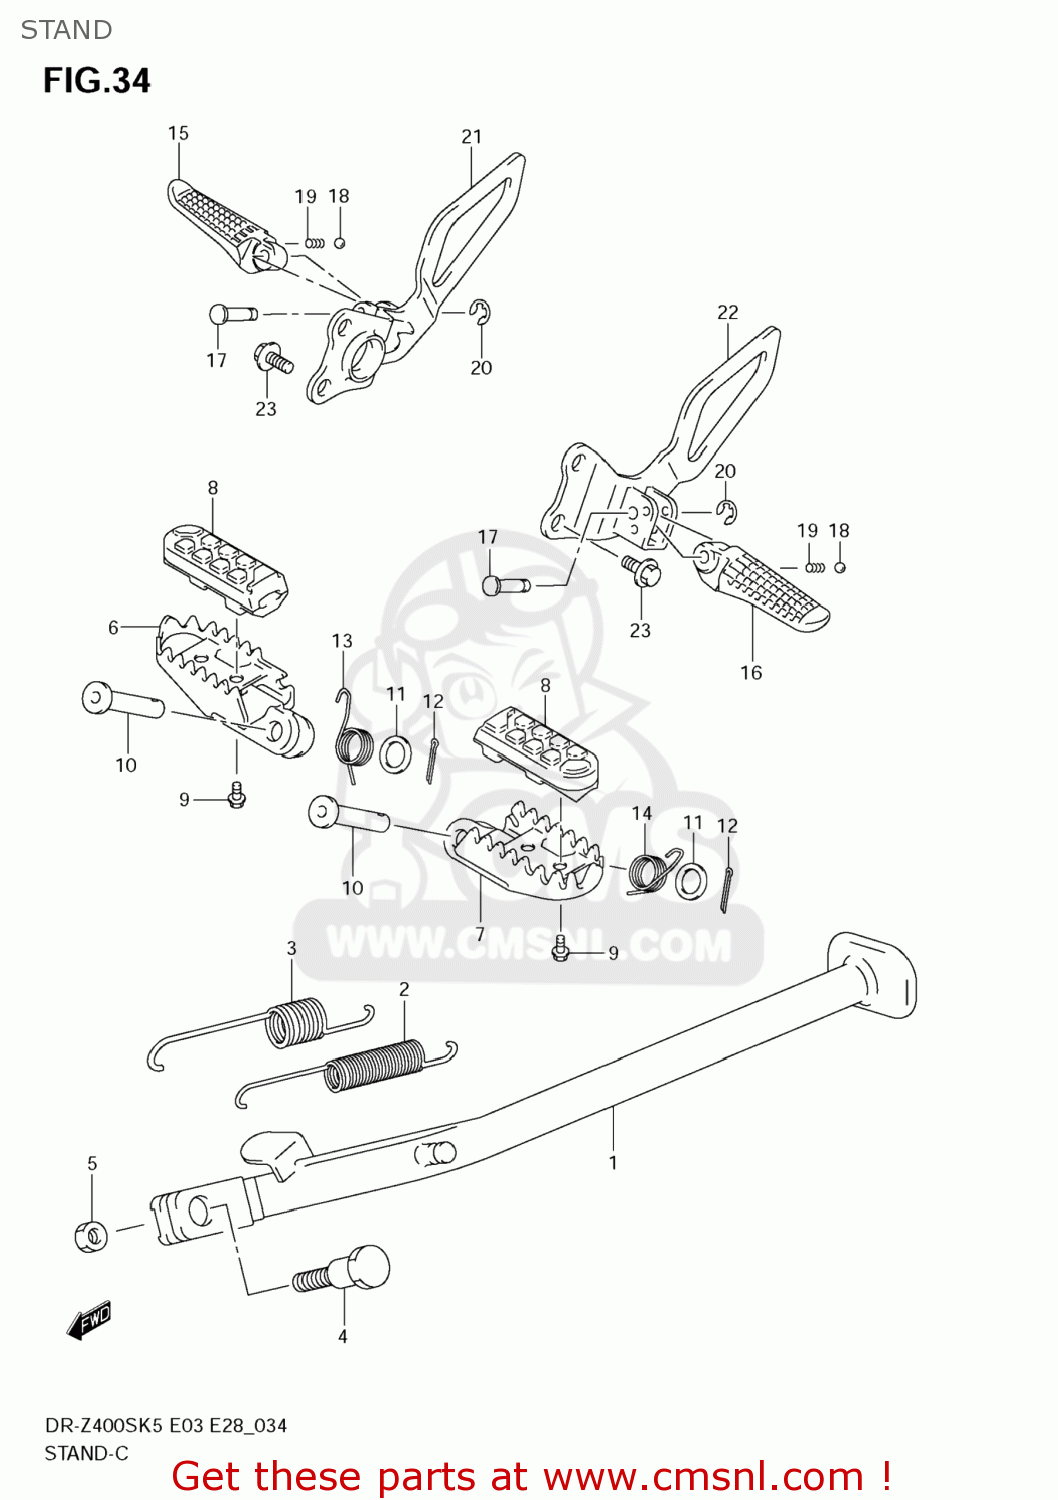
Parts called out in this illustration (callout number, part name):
1	STAND,PROP
2	SPRING
3	SPRING
4	BOLT(10X33)
5	NUT,PROP STAND
6	FOOTREST,R
7	FOOTREST,L
8	RUBBER,FOOTREST
9	BOLT
10	PIN(10X41.5)
11	WASHER
12	PIN
13	SPRING
14	SPRING
15	BAR,PILLION FOOTREST,R
16	BAR,PILLION FOOTREST,L
17	PIN
18	BALL
19	SPRING
20	E RING
21	BRACKET,PILLION,R
22	BRACKET,PILLION,L
23	BOLT
